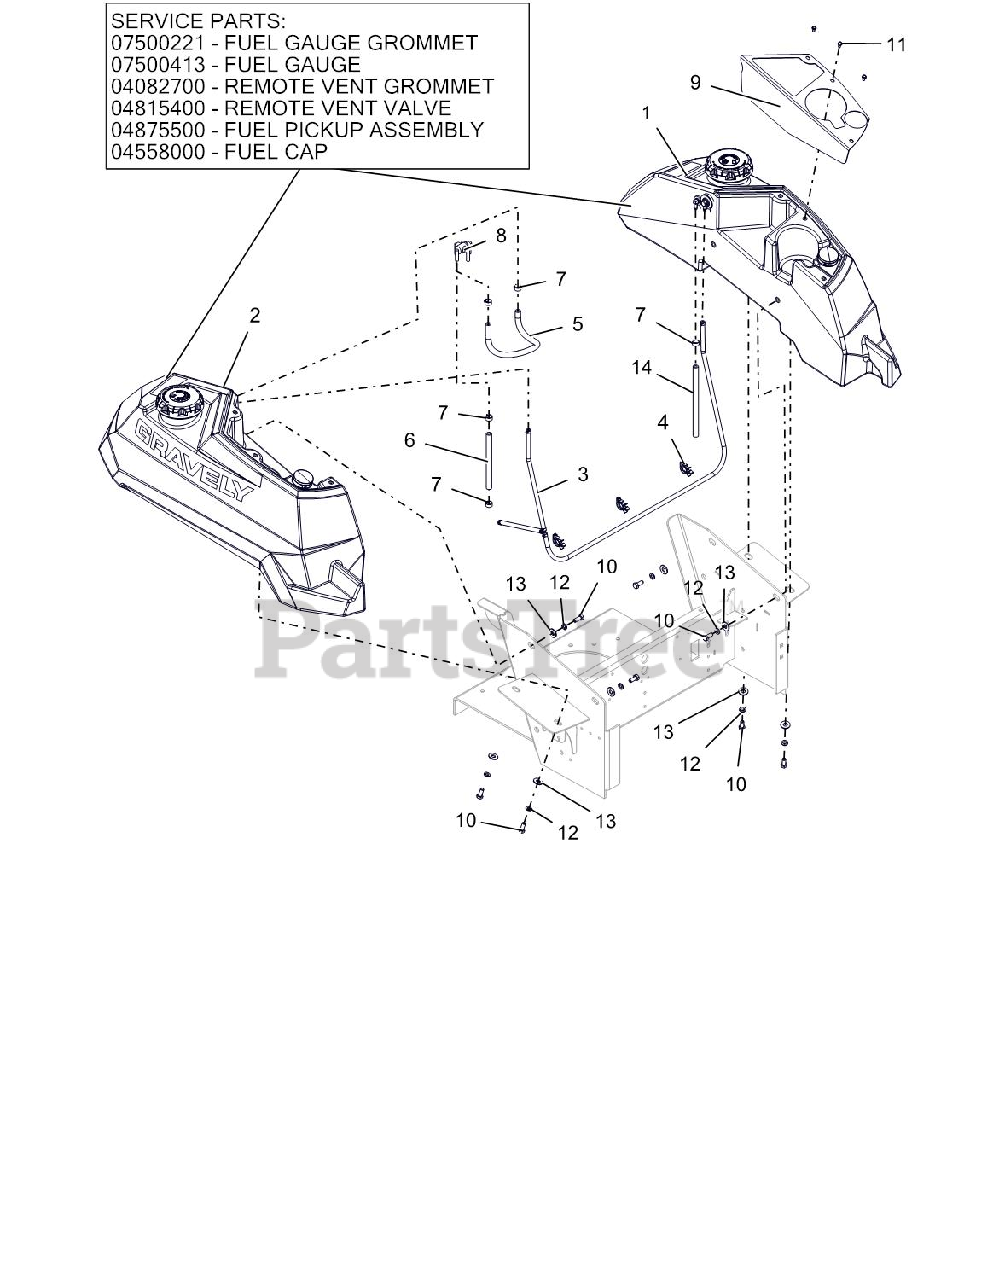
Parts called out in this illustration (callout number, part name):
1	ASM, LH - PT100 FUEL TANK
2	ASM, RH - PT100 FUEL TANK
3	ASM, VAPOR LINE
4	WIRE CLIP
5	HOSE, .25 LOW-PERM BULK GAS
6	HOSE, .25 LOW-PERM BULK GAS
7	CLAMP, FUEL LINE
8	VALVE, FUEL
9	PT100 CUPHOLDER PANEL - RED
10	@BLT-HEX .31-18X.75 GR5 YWZC
11	SCR-MCH 10-24X.38 HWHSTAINLESS
12	@WSHR-LK .31X.078 REG YWZC
13	@WSHR-FL-STL.38X.875X.083 YWZC
14	HOSE, .25 LOW-PERM BULK GAS
15	GROMMET, FUEL GAUGE
16	GAUGE, REMOTE SEALED FUEL
17	GROMMET, REMOTE VENT NITRILE
18	VALVE, 2-WAY
19	ASSM,LRG TANK FUEL PICKUP LINE
20	CAP, FUEL VENTIN AUTOLOCK
